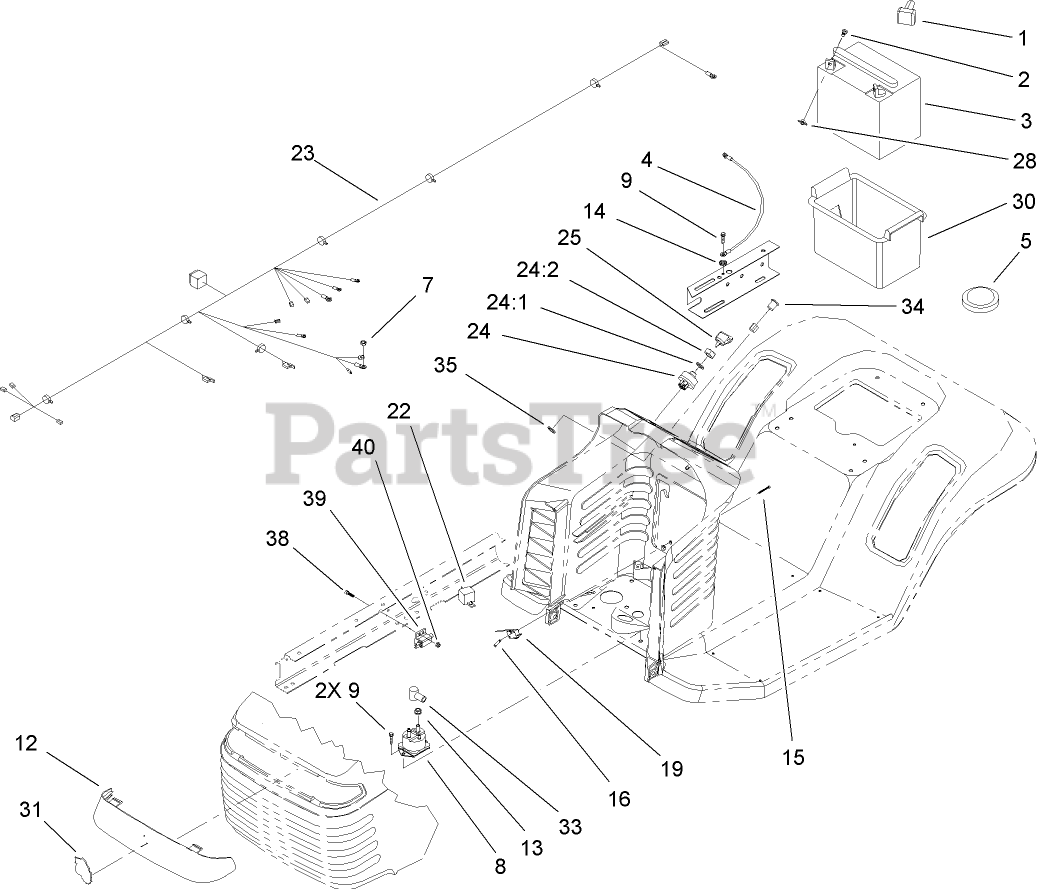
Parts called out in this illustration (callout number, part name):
1	BOOT-TERMINAL
2	SCREW-HH
4	WIRE ASM
5	SWITCH-SEAT
7	NUT-KEPS
8	SOLENOID-STARTER
9	SCREW-HWH
12	LENS-HEADLIGHT
13	NUT-KEPS
14	WASHER-LOCK/EXT
15	SCREW-HH
16	NUT-SPEED
19	SWITCH-MICRO
22	RELAY
23	HARNESS-WIRE
24:1	WASHER-LOCK
24:2	NUT-HH
25	KEY-IGNITION
28	NUT-WING
30	BOX-BATTERY
31	EMBLEM
33	BOOT-INSULATOR, TERMINAL
34	LIGHT-INDICATOR
35	NUT-PUSH-ON, CIRCULAR
38	SCREW-HSH
40	NUT-LOCK, NI
